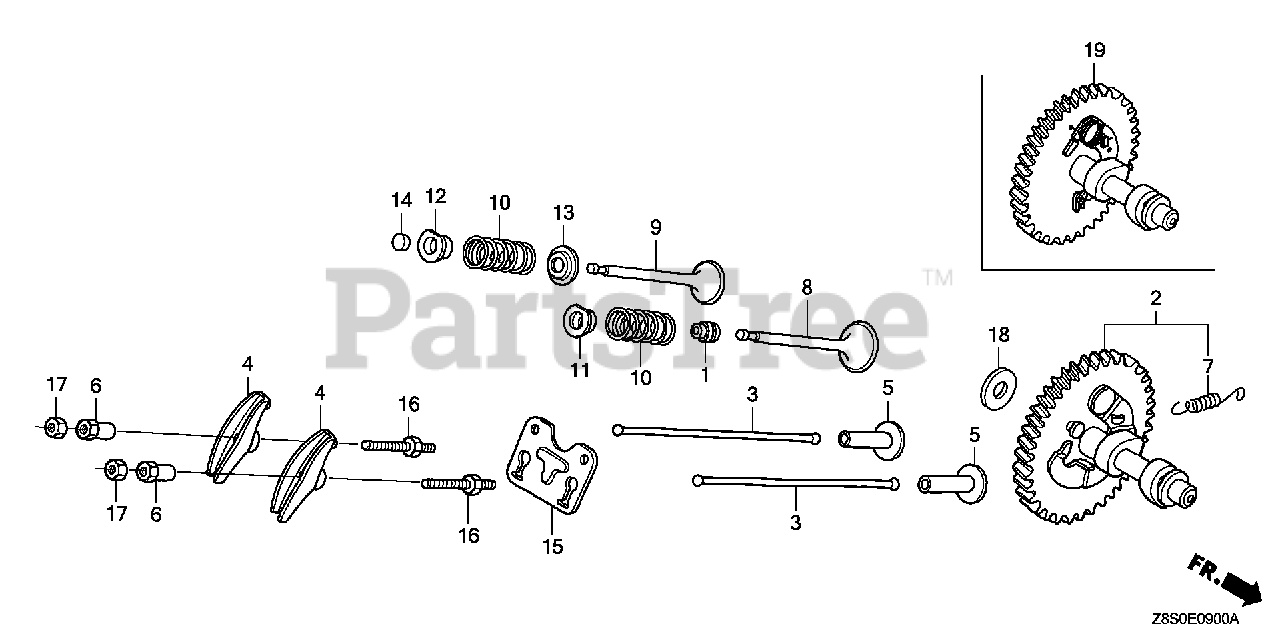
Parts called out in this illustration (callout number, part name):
1	SEAL, VALVE STEM
2	CAMSHAFT (STD) (PRESS FIT CAM)
4	ARM, VALVE ROCKER
5	LIFTER, VALVE
6	PIVOT, ROCKER ARM
7	SPRING, WEIGHT RETURN
8	VALVE, IN.
9	VALVE, EX.
10	SPRING, VALVE
11	RETAINER, IN. VALVE SPRING
12	RETAINER, IN. VALVE SPRING (EXHAUST SIDE)
13	SEAT, VALVE SPRING
15	GUIDE, PUSH ROD
16	BOLT, PIVOT (8MM)
17	NUT, PIVOT ADJUSTING
19	CAMSHAFT (STD) (PRESS FIT CAM)
